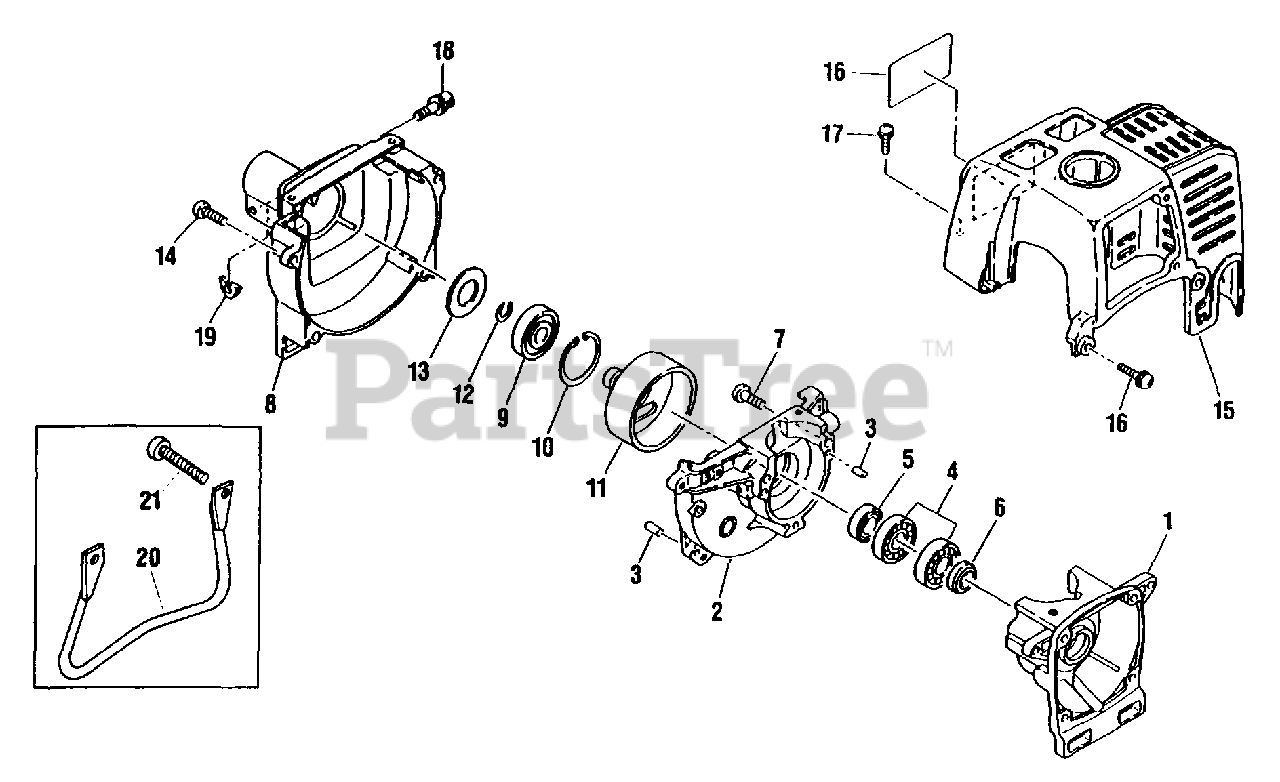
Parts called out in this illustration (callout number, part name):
1	CRANKCASE - REAR
2	CRANKCASE ASSY - FRONT
3	PIN, DOWEL
4	BEARING, BALL 6001
5	SEAL, OIL 12
6	SEAL, OIL 12
7	BOLT 5×25
8	CASE, FAN
9	BEARING, BALL 6201
10	RING, SNAP Ø32
11	DRUM, CLUTCH
12	RING, SNAP Ø12
13	WASHER, THRUST
14	SCREW
15	COVER, ENGINE
16	NAME PLATE
17	SCREW M5×16
18	BOLT M5×25
19	SHIM
21	SCREW M5×35
